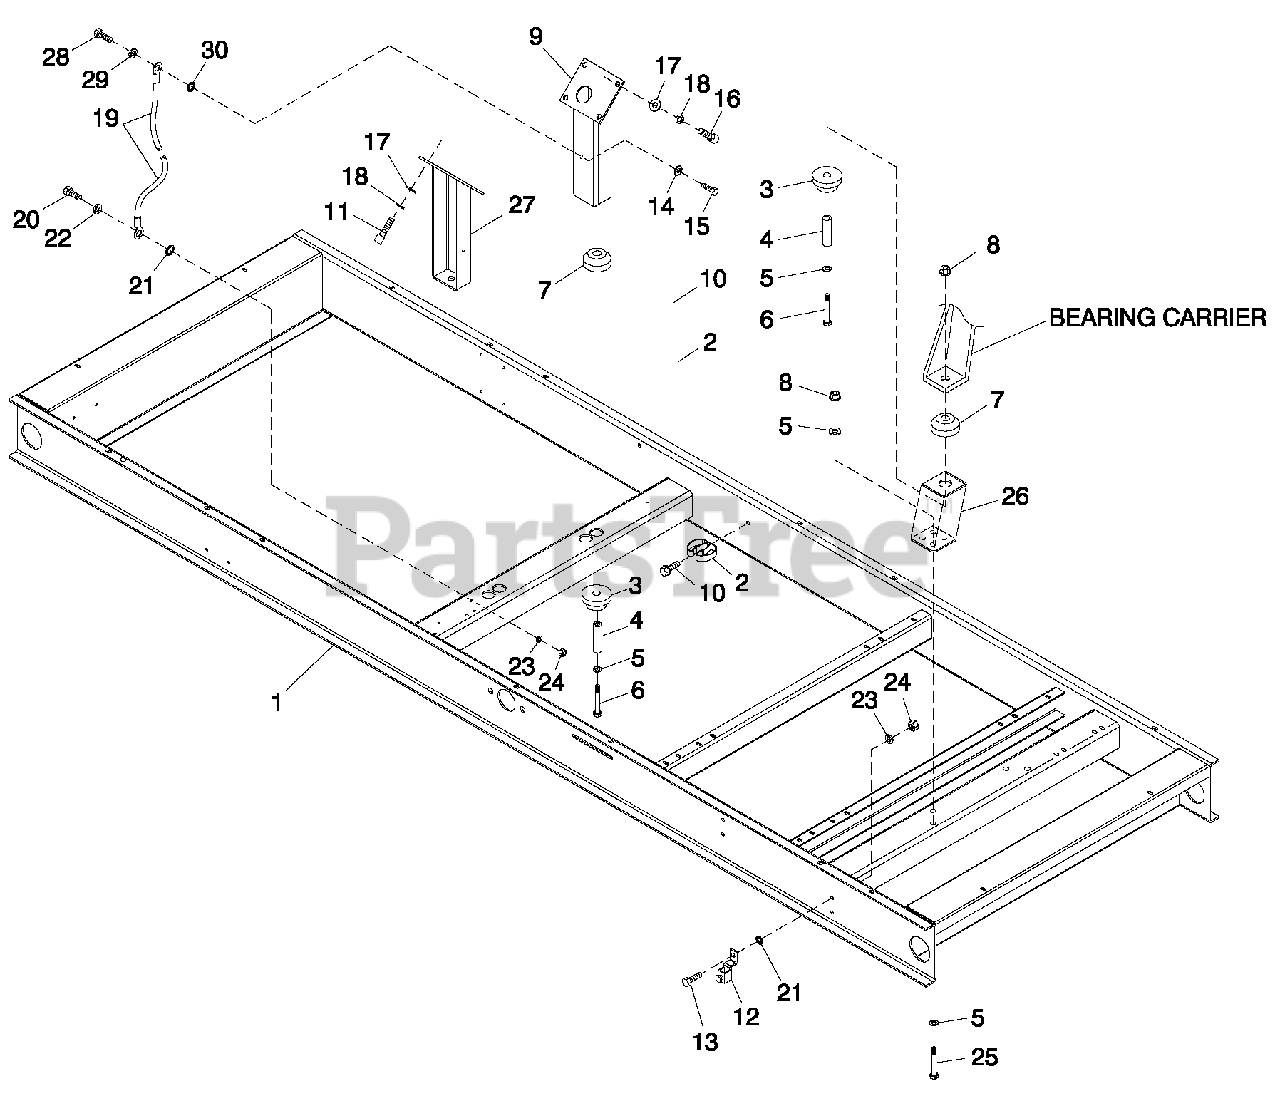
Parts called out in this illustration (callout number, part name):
1	BASE CPL 100-130KW6.8LGB
2	SPRING CLIP HOLDER .37-.62
3	DAMPENER VIBRATION
4	SPACER .49 X .62 X 1.87 PWDR/ZINC
5	WASHER FLAT M12
6	SCREW HHC M12-1.75 X 85 G8.8
7	DAMPENER VIBRATION 50 WHITE
8	NUT LOCKING M12-1.75
9	SUPPORT ENG 5.4L LH/RH 6.8L RH
10	SCREW HHTT M4-0.7 X 8 BP
11	SCREW SHC M10-1.5 X 60 G12.9
12	LUG SOLDERLESS 3/0-#4 X 13/32 CU
13	SCREW HHC M8-1.25X 25 G8.8
14	WASHER FLAT 1/4-M6 ZINC
15	NUT HEX M6X 1.0 G8YEL CHR
16	SCREW SHC M10-1.5 X 30 G12.9
17	WASHER FLAT 3/8-M10 ZINC
18	WASHER LOCK M10
19	ASSY WIRE 14.00"
20	SCREW HHC M8-1.25X 30 G8.8
21	WASHER SHAKEPROOFINT 3/8
22	WASHER LOCK M8-5/16
23	WASHER FLAT 5/16-M8 ZINC
24	NUT HEX M8-1.25 G8YEL CHR
25	SCREW HHC M12-1.75 X 40 G8.8
26	TOWER GBCOMPROD C5
27	SUPPORT ENGINE 6.8L LH SIDE
28	SCREW HHC M6-1.0 X 30 G8.8
29	WASHER LOCK M6-1/4
30	WASHER SHAKEPROOF INT 1/4
